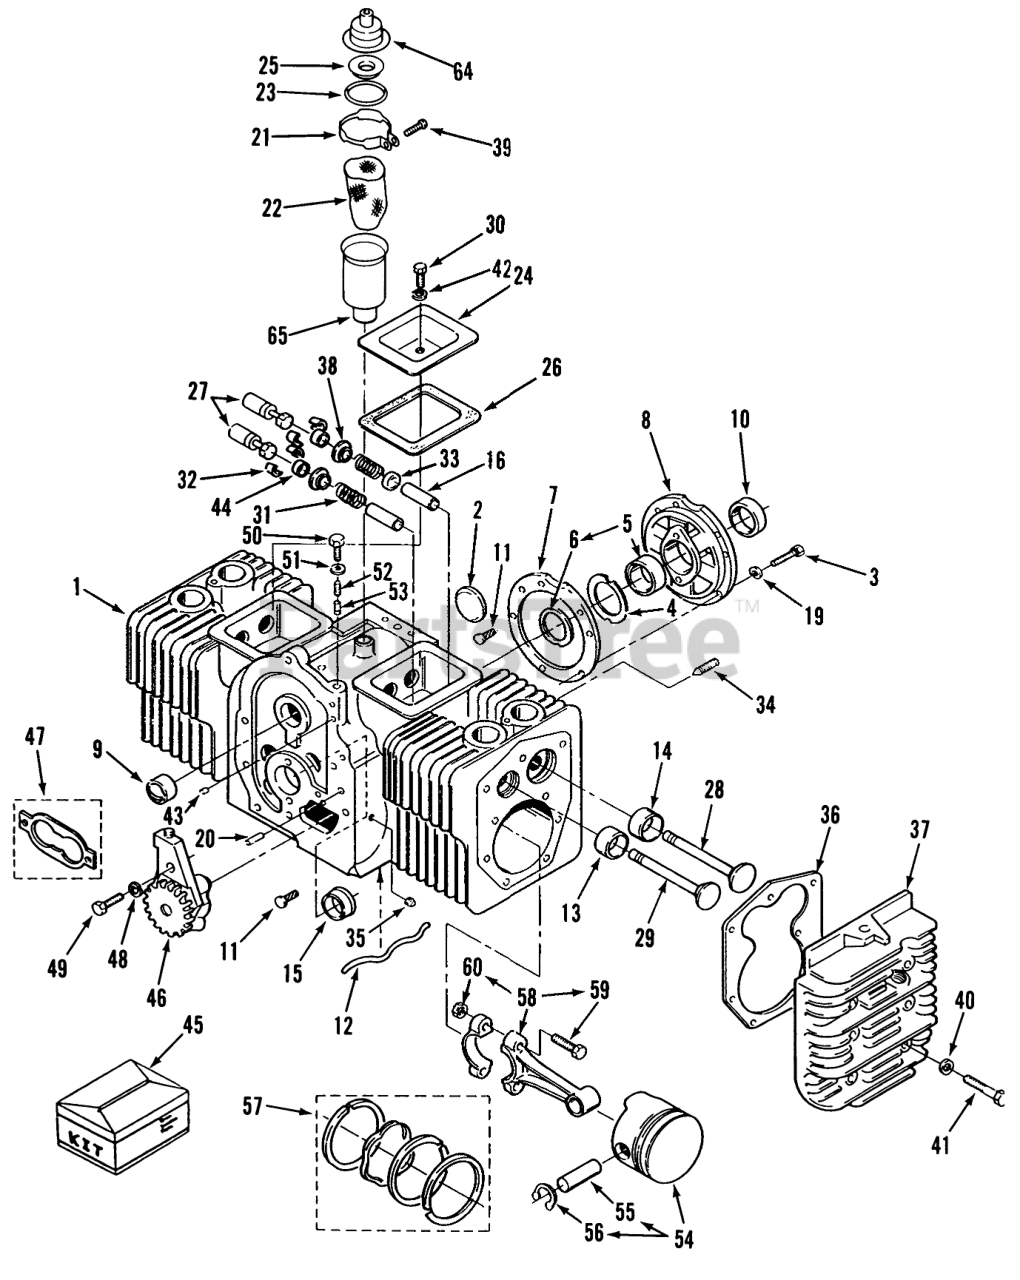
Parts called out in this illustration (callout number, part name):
1	Short Block
2	Plug
3	Bolt 3/8-16x 1-1/4
4	Shim 0.005"
5	Rear Crankshaft Bearing-STD
6	ThrustWasher
7	Gasket
8	Bearing Plate
9	Camshaft Brg
10	Oil Seal
11	Screw
12	Oil Tube
13	Standard
14	Standard
15	Standard
16	Exhaust Valve Guide
19	Lockwasher 3/8
20	Pin
21	Clamp
22	Baffle
23	Seal
24	VALVE-COVER L.H.
25	Screen
26	Gasket
27	Tappet
28	Intake Valve
29	Exhaust Valve
30	HHCS 1/4-20 X 1 3/4
31	Spring
32	VALVE SPRING LOCK
33	Seal
34	Screw
35	Plug
36	Gasket
37	Right Side
38	Washer
39	Screw #8 x 3/4
40	Washer
41	Special Bolt 2.375" Long
42	Washer
44	Cap-Valve
45	Engine Gasket Kit
46	Oil Pump
47	Oil Pump Gasket Kit
48	Washer-Lock
49	Bolt
50	Bolt
51	Washer
52	Spring
53	Piunger
54	Piston (Includes Pin & Retaining Ring)-STD
55	Pin-Piston
56	Retaining Ring
57	Standard
58	Rod w/Bolts & Nuts-STD
59	Rod Bolt
60	Nut
64	Breather Cap & Valve
65	Breather Tube
